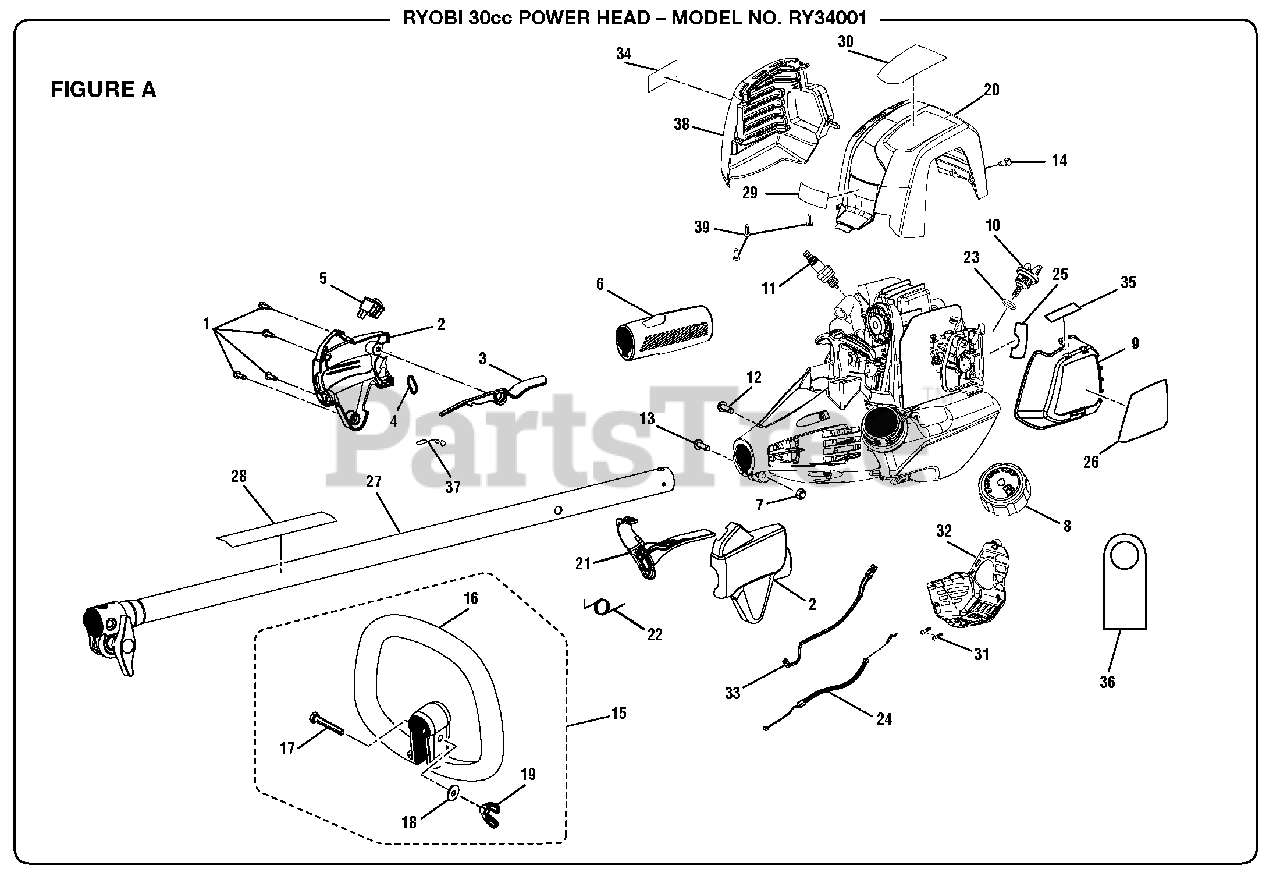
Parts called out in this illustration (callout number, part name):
1	Screw (M4 x 20 mm)
2	Control Handle Assembly
3	Trigger Lock
4	Strap Hanger
5	Switch (Momentary Contact)
6	Rear Handle
7	Hex Nut (M6.3 x 1)
8	Fuel Cap Assembly
9	Air Box Cover
10	Oil Cap/Dipstick
11	Spark Plug (Champion RY4C)
12	Screw (#8-16 x 5/16 in.)
13	Bolt (M6 x 1 x 20 mm)
14	Screw (M5 x 11 mm)
15	Front Handle Assembly
16	Front Handle
17	Bolt (1/4-20 x 40 mm)
18	Washer (1/4 in.)
19	Wing Nut (1/4-20)
20	Top Cover
21	Throttle Trigger
22	Throttle Trigger Spring
24	Throttle Cable
25	Hot Surface Label
26	Starting Label
27	Upper Boom Assembly
28	Warning Label
29	Logo Label
30	X430 Label
31	Screw (#6-19 x 1/2 in.)
32	CE Cover (Bottom Cover)
33	Lead Assembly
34	Combustion Warning Label
35	Choke Label
36	Oil Hang Tag
38	Muffler Housing
39	Screw (M4 x 12 mm)
